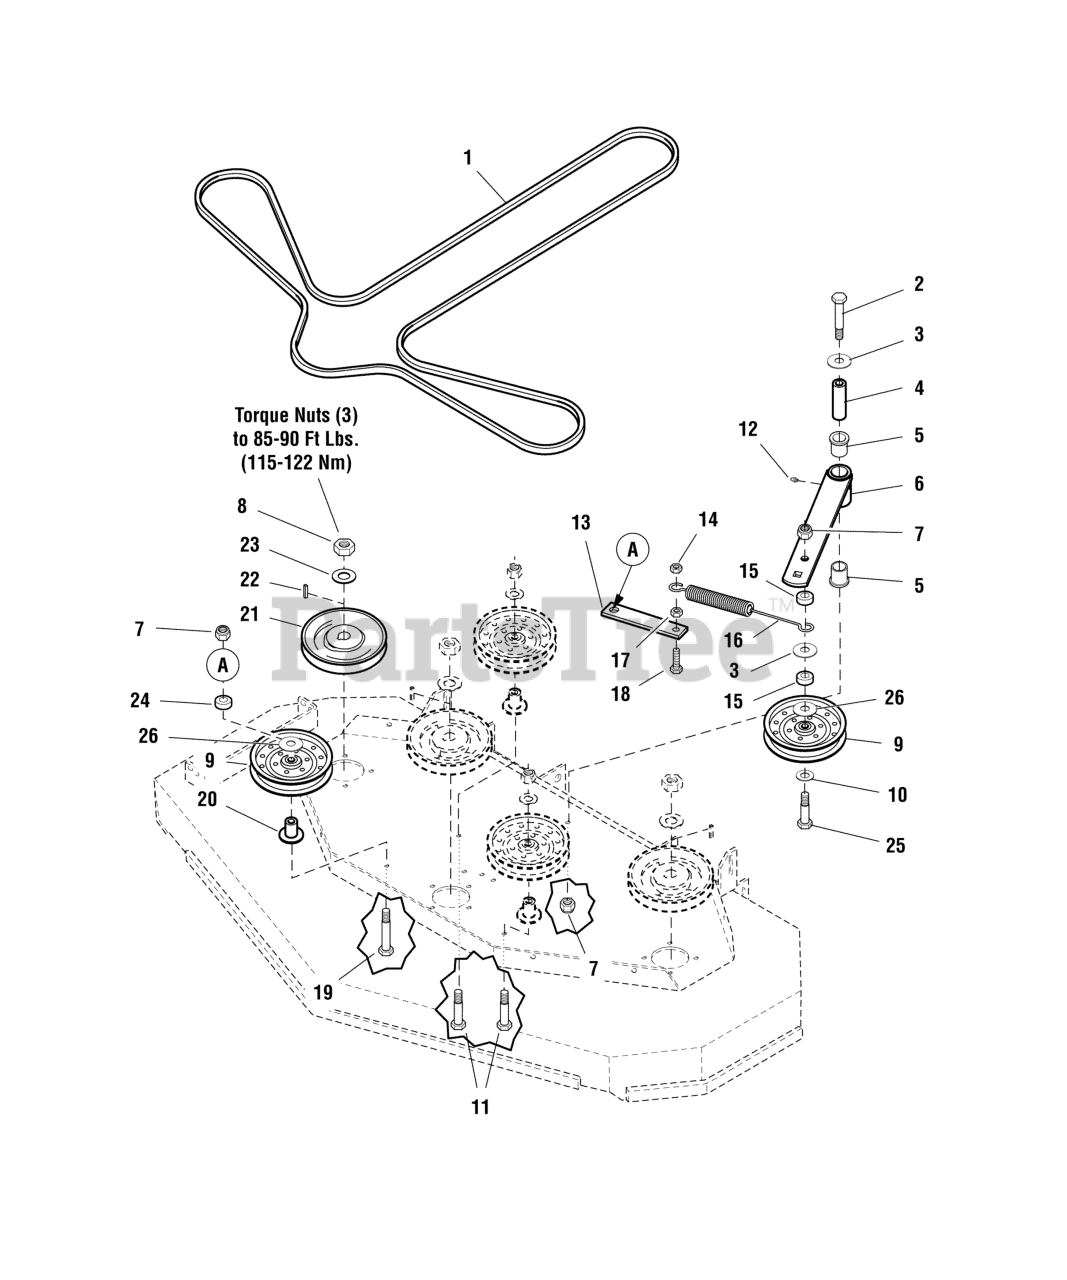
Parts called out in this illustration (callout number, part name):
1	BELT, 5V, 175.90EL, LG ARAMID, WRPD, RC
2	BOLT, 1/2-13 X 4-1/2" GD5
3	WASHER, 1/2" USS
4	SPACER, .52 X 1.00 X 3.50
5	BUSHING, FLANGE
6	ASSM, IDLER ARM
7	NUT, Hex Flange, Nylock, 1/2-13
8	NUT, 3/4-16 HEX
10	WASHER, 1/2" GD9 YZ
11	BOLT, 1/2-13 X 3" GD5 CZ
12	GREASE FITTING, 1/4-28 STRAIGHT
13	MOUNT, IDLER SPRING - RED
14	NUT, 3/8-16 HEX SIDE LOCK
15	SPACER, .52 X 1.00 X .38
16	SPRING, EXTENSION, SWIVEL END
17	NUT, 3/8-16 HEX SERRATED FLANGE
18	BOLT, 3/8-16 X 1-1/4" GD5 CZ
19	BOLT, 1/2-13 X 3-1/2, HEX HD, GD5, CZ (SV)
20	IDLER MOUNT
21	PULLEY, 6.93 EOD X 25MM, SPLIT
21	PULLEY, SPINDLE, 6.5 OD X 25MM, SPLIT ST
21	PULLEY, BC66 X 25MM, SPECIAL
22	KEY, 1/4" SQ. X 1-1/4
23	WASHER, 3/4 BELLEVILLE
24	SPACER, .52 x 1.00 x .44
25	BOLT, 1/2-13 X 3" GD5 CZ
26	SHIELD, PULLEY BEARING
